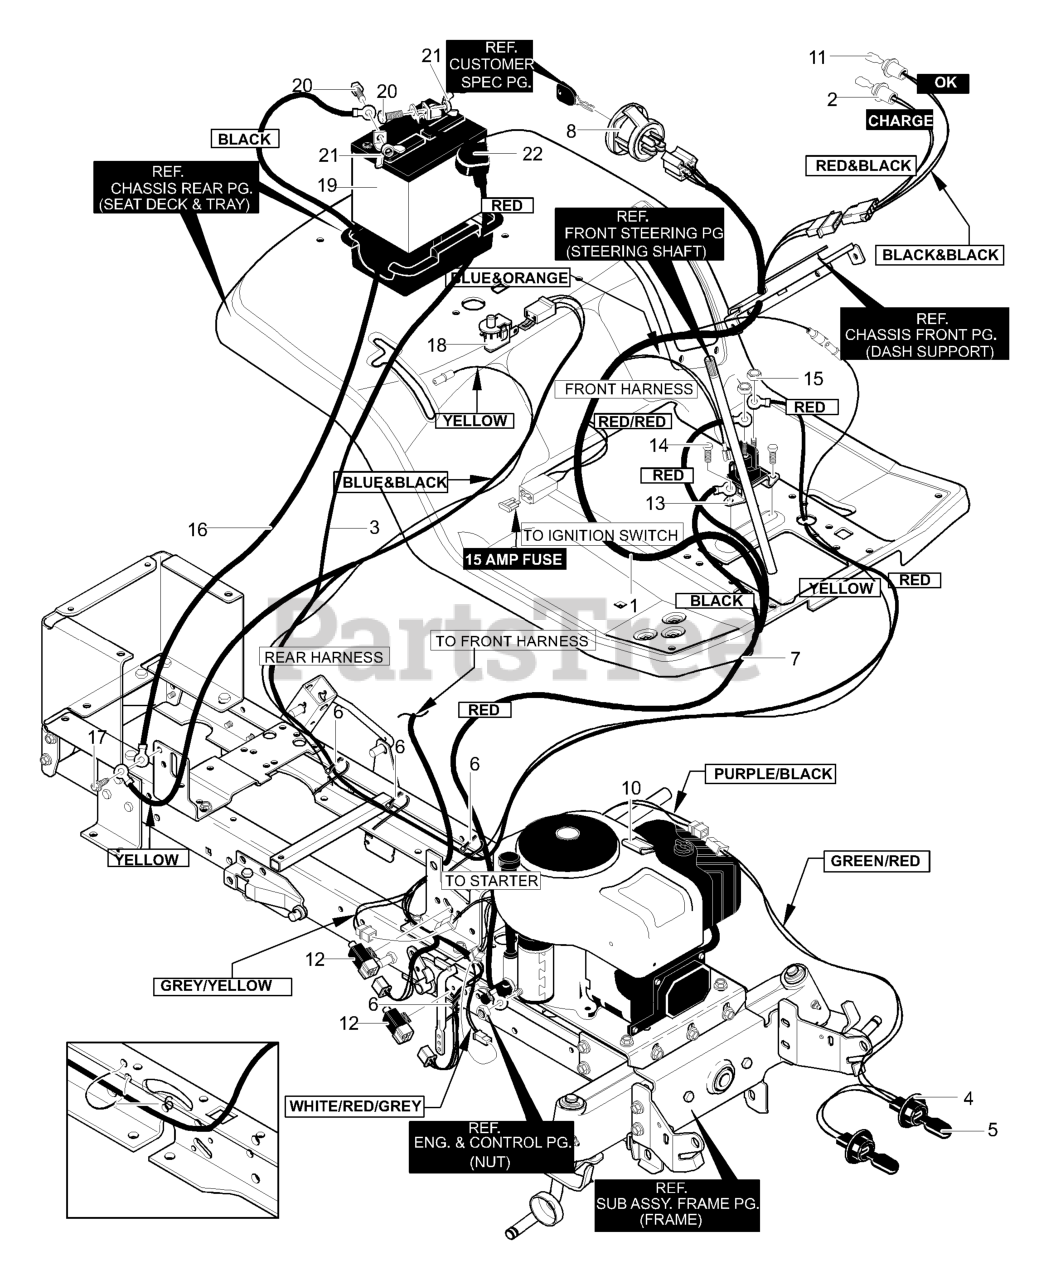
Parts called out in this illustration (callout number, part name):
1	Wire Harness w/Indicator
2	Harness, Ind. PTO/CHG
3	Wire Harness, Rear
4	Wire Harness for Headlights
5	Bulb, Headlamp
6	Cable Tie
7	Wire, Lead Solenoid to Starter
8	Switch, Ignition
10	Wire Clip, Adhesive
11	Bulb, Indicator
12	Switch, Limit
13	Solenoid
14	Screw 1/4x.50
15	Nut, 1/4-20
16	Ground Wire
17	Screw, 1/4x.75
18	Seat Switch
19	Battery 5 Plate
20	Bolt, 1/4-20X.63
21	Wing Nut
22	BOOT, Battery Terminal, Positive
